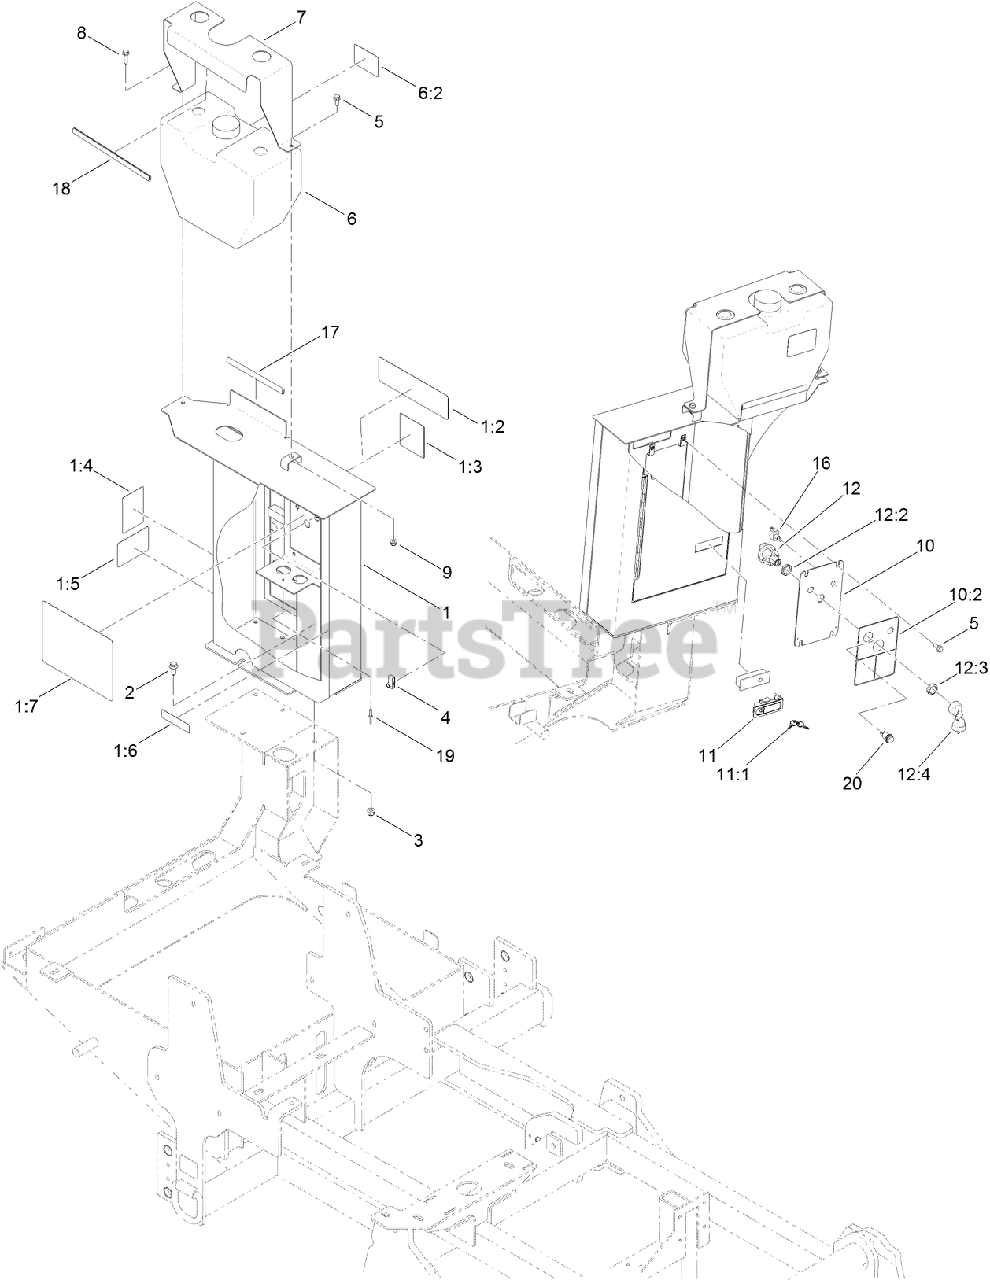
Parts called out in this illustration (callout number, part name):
1	REAR CONTROL BOX ASM
1:2	DECAL-SAFETY
1:3	DECAL-DANGER, NO RIDERS (REAR)
1:4	DECAL-DANGER, BACK UP
1:5	DECAL-RAISE AND LOWER
1:6	DECAL-ARRESTER, SPARK
1:7	DECAL-SERVICE
2	SCREW-HHF
3	NUT-LOCK, NI
5	SCREW-HHF
6	TANK COOLANT ASM
6:2	DECAL-ANTIFREEZE
7	BRACKET-BOTTLE, ANTI-FREEZE
8	SCREW-HHF
9	NUT-LOCK, HHF
10	REAR CONTROL PANEL ASM
10:2	DECAL-REAR CONTROL
11	LATCH-TRIGGER, RAISED (W/LOCK)
12	IGNITION SWITCH ASM
12:2	NUT-HEX
12:3	NUT-FACE
12:4	IGNITION KEY SET
16	SWITCH-TOOGLE, SPST, ON-OFF (SEALED)
17	TRIM-TANK
18	TRIM-TANK
19	RIVET-POP
20	LAMP-INDICATOR, LED
